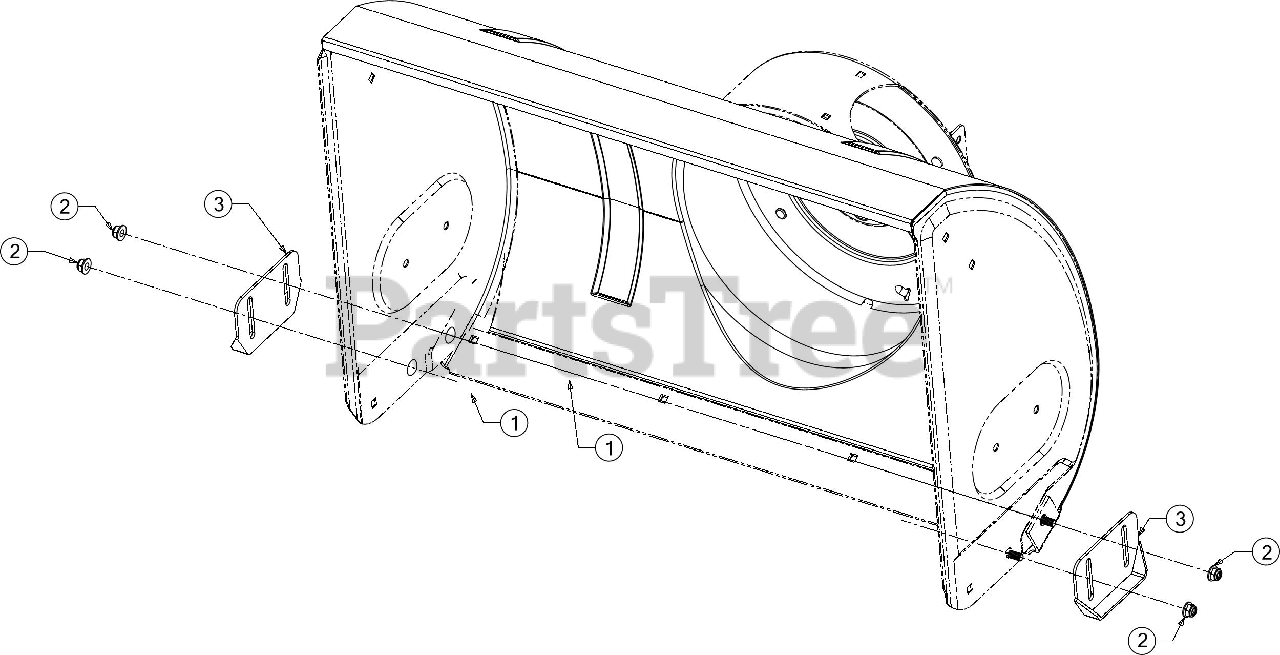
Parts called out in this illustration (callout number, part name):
1	CARRIAGE BOLT 5/16-18 x .75
2	FLANGE LOCK NUT 5/16-18
3	SLIDE SHOE
